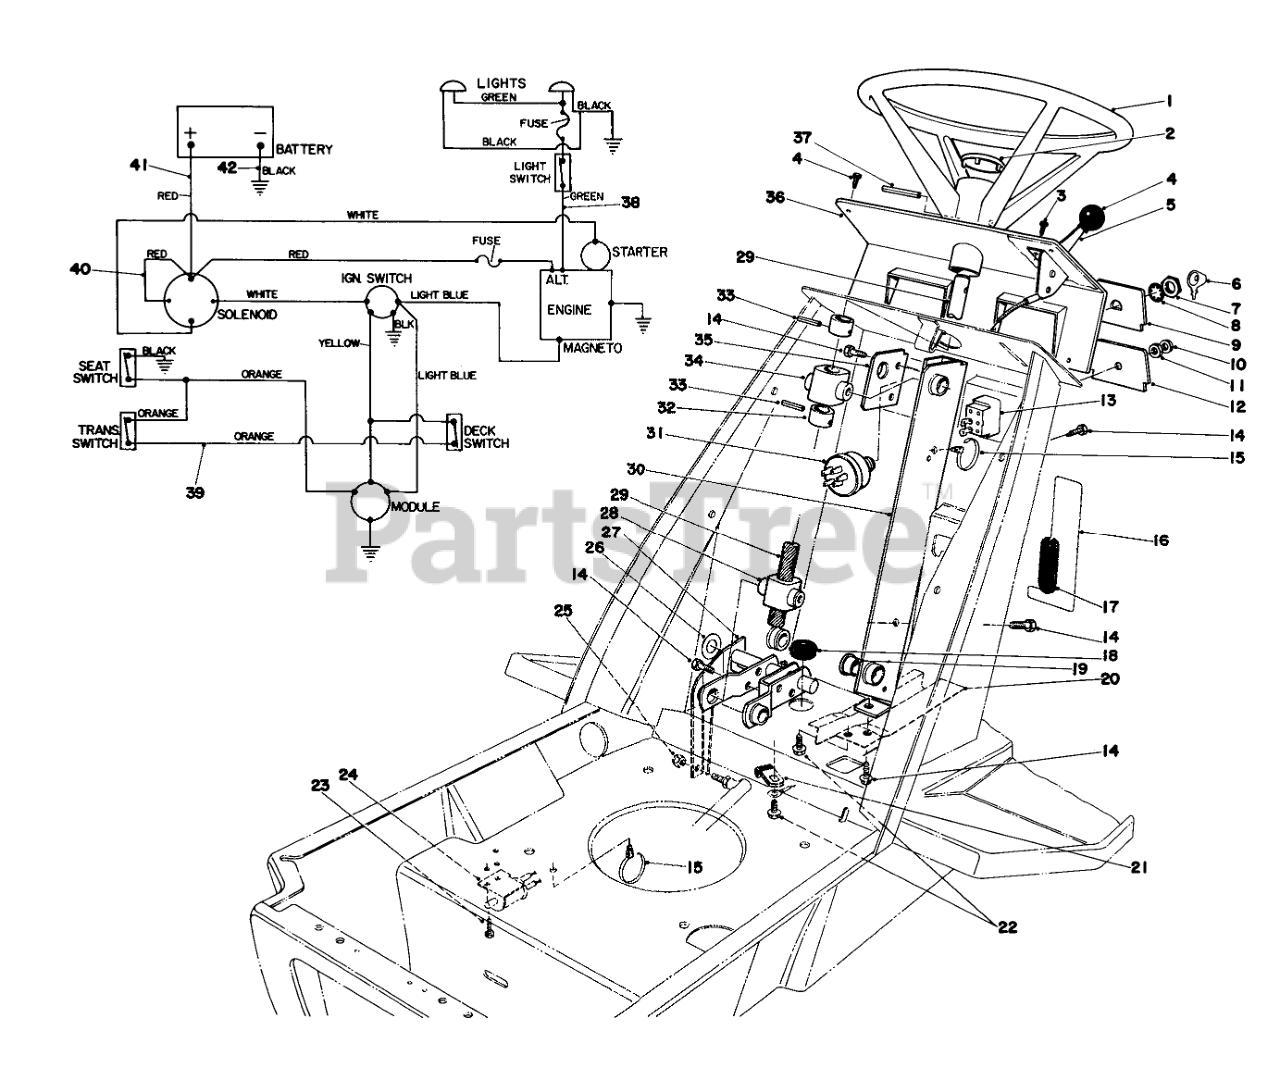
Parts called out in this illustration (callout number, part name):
1	Steering Wheel
2	STRG WHEEL INSERT
3	SCREW-HWHTF
4	KNOB-CONTROL
5	Throttle Control (Incl. Ref. #4)
6	Key
7	NUT-HH
8	WASHER-TOOTH, INTERNAL
9	DASH PANEL INSERT
10	NUT-BULB
11	NUT-LOCK
12	DASH PANEL INSERT
13	Light Switch (Incl. Ref. #11-12)
14	SCREW-HWHTF
15	Push Mount Tie
16	Decal-Deck
17	EDGE MOULDING
18	GROMMET
19	BEARING-FLANGE
20	WIRE HARNESS SHLD B
21	CLIP-FUEL LINE
22	SCREW-HWH
23	SCREW-TAPTITE
24	DECK INTERLOCK SWITCH
25	Nut
26	WASHER
27	STEERING LINK WA BO
28	FOLLOWER STEER SHAFT
29	STEERING SHAFT
30	STRG BRKT B
31	Ignition Switch (Incl. Ref. #7-9)
32	STRG SHAFT COLLAR
33	PIN-SPRING
34	BRG STEERING SHAFT
35	STRG BRG SUPPORT
36	DASH PANEL
37	PIN-ROLL
38	WIRE HARNESS
39	Wire Harness
40	SOLENOID WIRE
41	WIRE ASM
42	WIRE ASM
